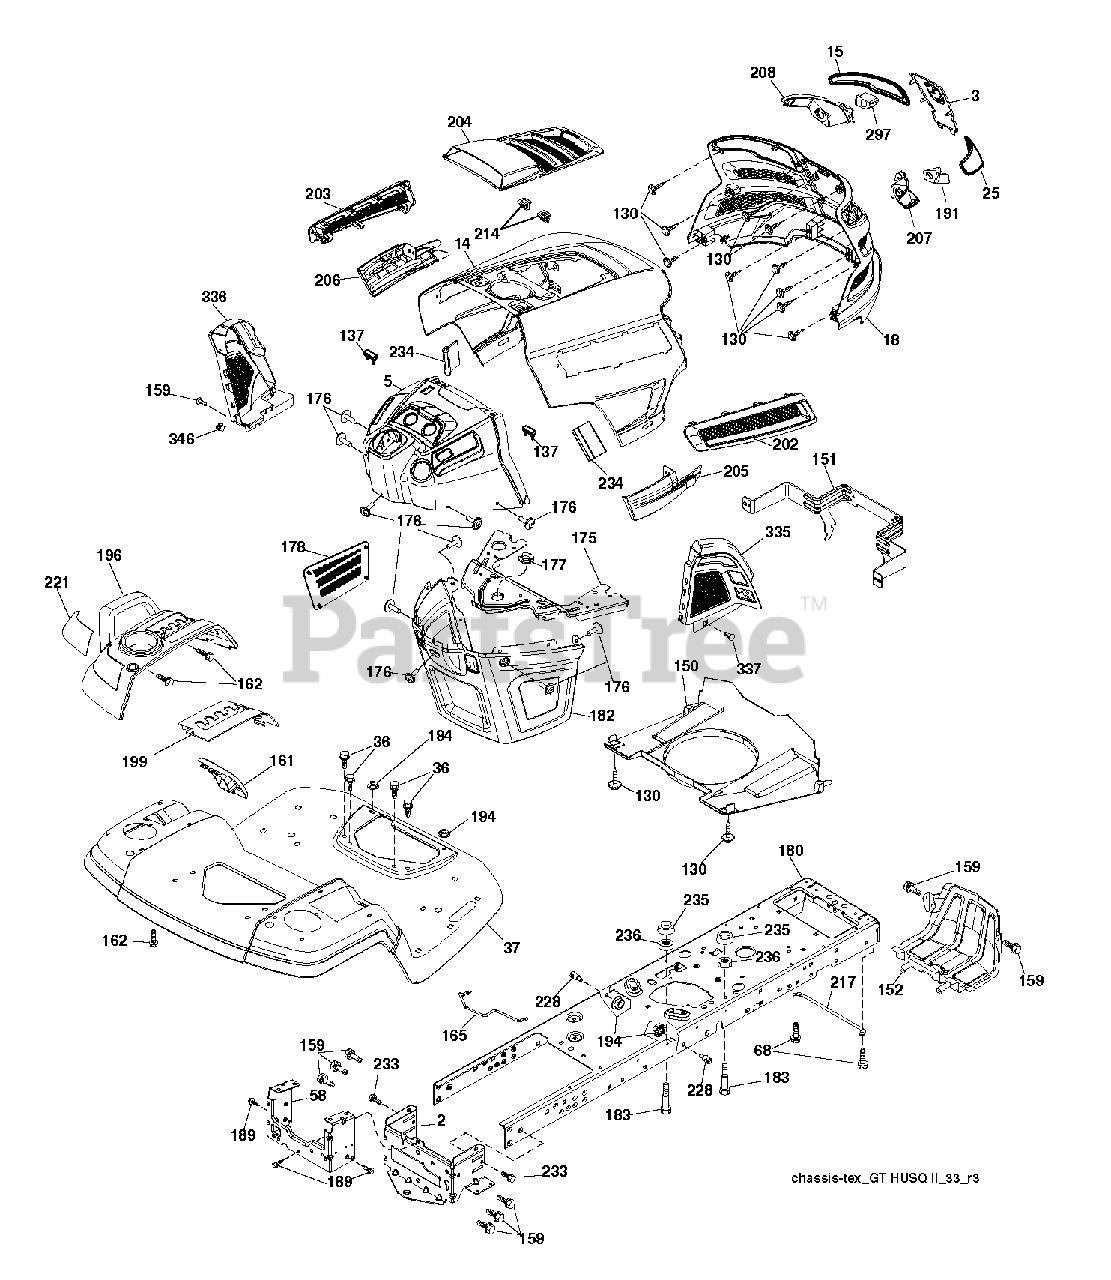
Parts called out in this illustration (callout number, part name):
2	DRAWBAR.LOWER.2PC.18/22
3	APPLIQUE.SUBASM.GT.HUSQ.II
5	DASH.UPP.GT2.DUAL.RD.PTO.MCHOK
14	HOOD.ASM.HUSQVARNA.GT.TEX.ORAN
15	LENS.HEADLIGHT.LH.GTII.2011
18	GRILLE.SUBASM.GT.HUSQ.II
25	LENS.HEADLIGHT.RH.GTII.2011
36	SCREW 5/16"
37	FENDER.PNT.TX.GT.CH/FW/DL.HUSQ
58	DRAWBAR.UPPER.2PC,LRG.FENDER
68	SCREW LT
130	SCREW.#10 X 0.750.BOS
137	BUMPER DASH
150	AIR.DUCT.GTV.BLACK
151	BRACKET.PIVOT.HOOD.GT.HUSQ.II
152	SHIELD.BROWNING.PNT.GT.V2
159	SCREW, 3/8-16X3/4
161	CONSOLE.WINDOW.FUEL.HUSQ.GT
162	SCREW.HI-LO.CONSOLE
165	SUPPORT.TANK.REAR.B/TE
175	PLATE.CROSSMEMBER.HUSQ
176	SCREW.#10-24X5/8.RN.QU
177	BUSHING, STEERING
178	CARGO.ASM.NET.TXGT.W/C
180	CHASSIS.STAMPING.LT/GT
182	DASH.LOWER.COMMON.12V.ADAPTOR
183	BOLT.5/16-18X1-1/4 FULL THD
189	SCREW
191	INSERT.REFLECTIVE.RH.HUSQ.GTII
194	NUT LOCK HEX FLANGE 5/16-18
196	CONSOLE.ASM.DECKLIFT.HUSQGT.DL
199	PLATE.DECK.LIFT.HUSQVARNA.GT
202	VENT.SIDE.RH.GT.HUSQ.II.
203	VENT.SIDE.LH.GT.HUSQ.II.498
204	VENT.TOP.HUSQ.GT2
205	SIDE.TRIM.RH.GT.HUSQ.II
206	SIDE.TRIM.LH.GT.HUSQ.II.GRAY
207	BEZEL LIGHT.RH.GT.II.MYLAR
208	BEZEL LIGHT.LH.GT.II.MYLAR
214	CLIP.RETAINER.TINNER.
217	ROD.PIVOT.HOOD
221	REFLECTOR.LH.TEX GT HU
228	STUD.FASTNER.W/ANTI-ROTATE
233	BOLT.SHOULDER
234	BUMPER.HOOD.TEX.HUSQVARNA
235	SPACER FENDER
236	NUT.CENTERLOCK.5/16-
297	INSERT.REFLECTIVE.LH.HUSQ.GTII
335	COVER.RH.CLOSE.OUT.BLACK
336	COVER-LH.LOWER.DASH.GT2.BLACK
337	CLIP.XMAS.TREE.ITW.2622-00
346	CLIP,INSULATOR
